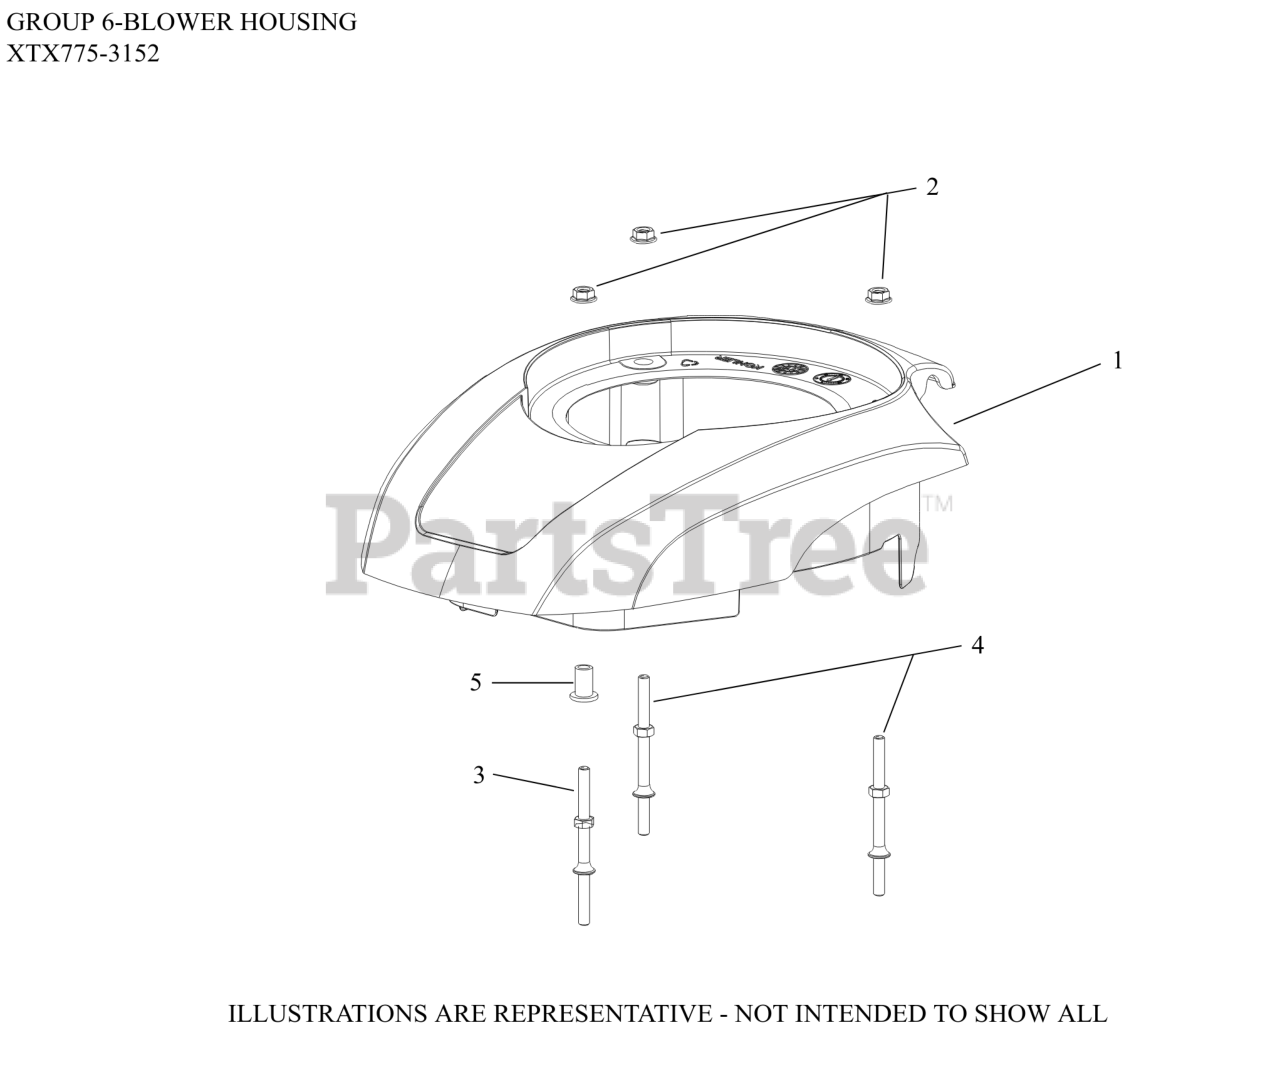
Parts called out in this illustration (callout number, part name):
1	COVER, ENGINE
2	NUT, HEX FLANGE (M6) - USE 14 100 16-S
3	STUD-USE 14 072 25-S
4	STUD-USE 14 072 26-S
